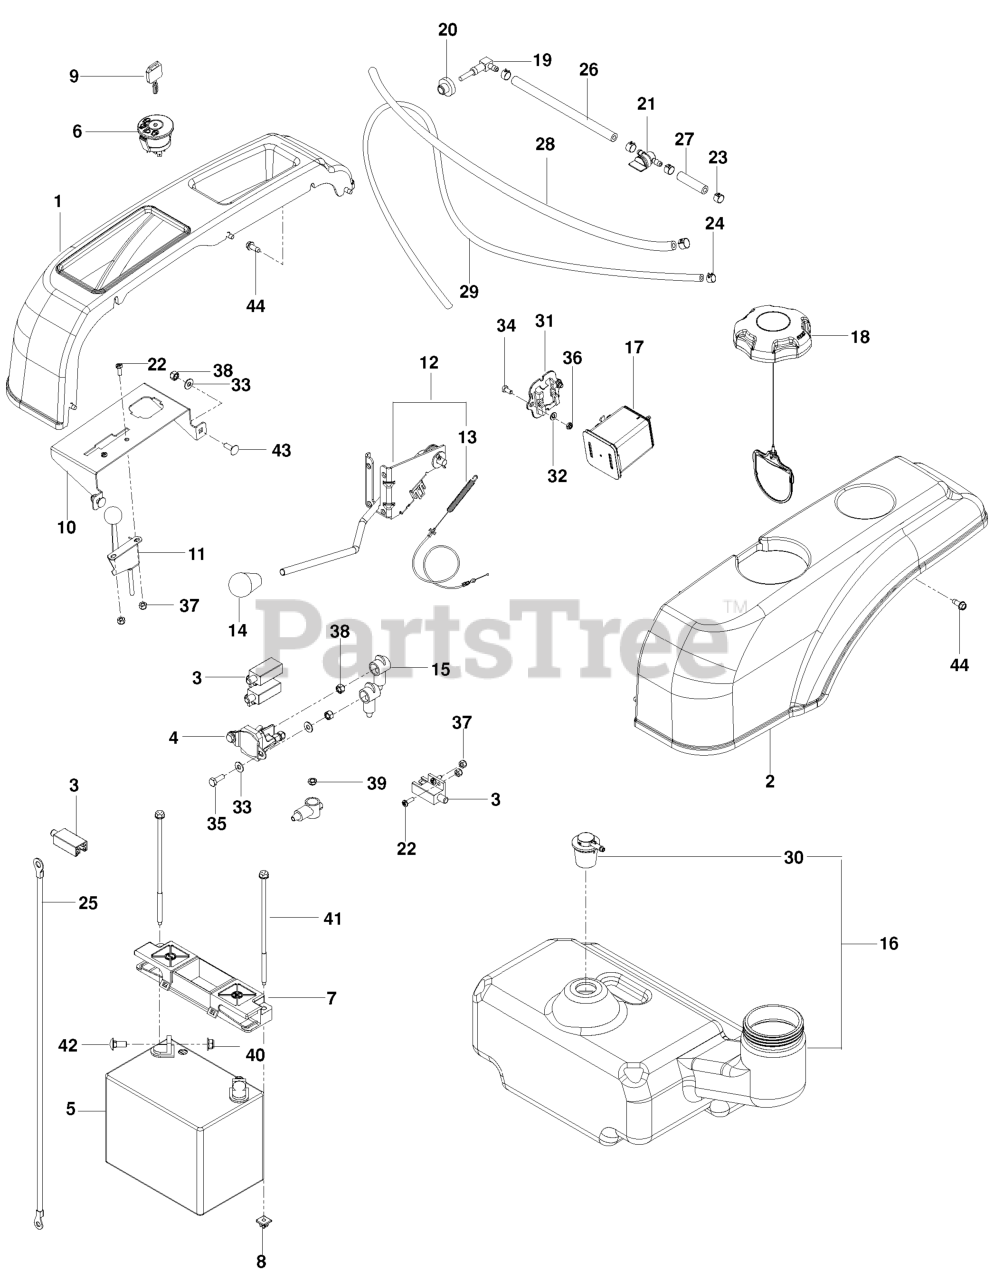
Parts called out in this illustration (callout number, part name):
1	FENDER, RZ 30/38 RT
2	FENDER, RZ 30/38 LT
3	SWITCH, INTERLOCK
5	BATTERY, 12 V 330 AMP
6	RP IGNITION SWITCH
7	BATTERY HOLD DOWN
8	PUSH NUT-NYLON
9	KEY
10	MOUNT, CONTROLS, BLK
11	CABLE, THROTTLE
12	ASM, CLUTCH ENGAGE W/CABLE
13	CABLE.CLUTCH.38".SERVICE
14	KNOB - SHIFT
15	TERMINAL COVER-SM
16	TANK, FUEL w/ VALVE
17	CANNISTER, CARBON
18	CAP, FUEL
19	ELBOW W/FILTER
20	TANK FITTING
21	FUEL VALVE
22	SCREW #10-24 X 5/8
23	HOSE CLAMP
24	CLAMP, HOSE
25	BATTERY CABLE, NEGATIVE
26	HOSE 1/4 X 8
27	HOSE 1/4 X 2"
28	FUEL LINE 24"
29	HOSE, FUEL 3/16" X 42"
30	VALVE, ROLLOVER, GROMMET
31	BRACKET, CANISTER
32	FLAT WASHER 5/16 SAE
33	WASHER 1/4 SAE
34	HCS 5/16-18 X 5/8 GR 5 ZD
35	HCS 1/4C X 3/4 HCS
36	5/16-18 THIN PROF NY
37	NUT 10-24 NYLOC
38	NUT.1/4-20.HEX.NYLOC.ZD
39	JAM NUT 1/4C (2 2 PW01)
40	5/16-18 NYLOC FLANGE NUT
41	BOLT - 1/4-20 X 7.5
42	BOLT 5/16C X 3/4" CARRIAGE
43	RHSNB 1/4C X 3/4
44	SCREW 1/4 X 5/8
